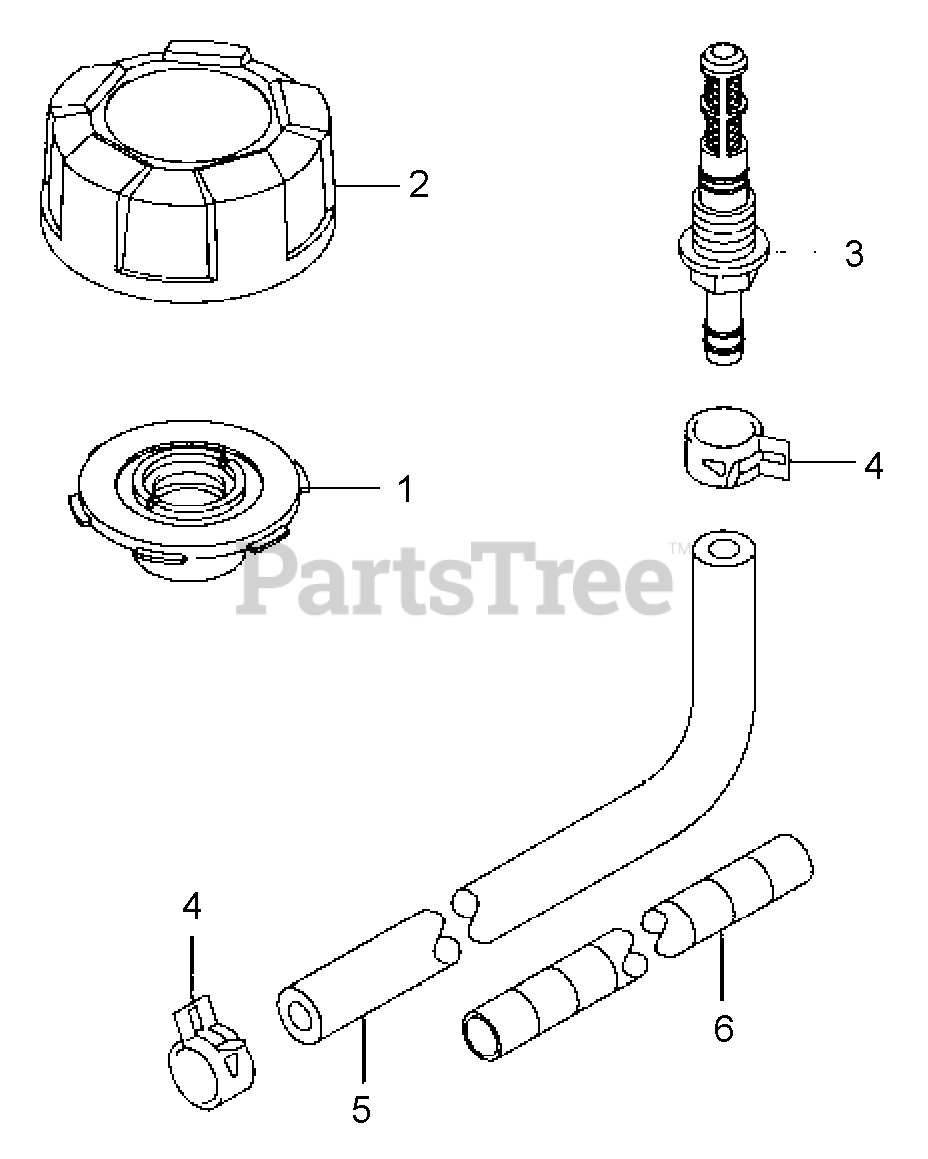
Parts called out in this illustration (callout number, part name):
3	Joint, In Tank Filter
4	Clamp
5	Tube, 6.35x12.7x285
